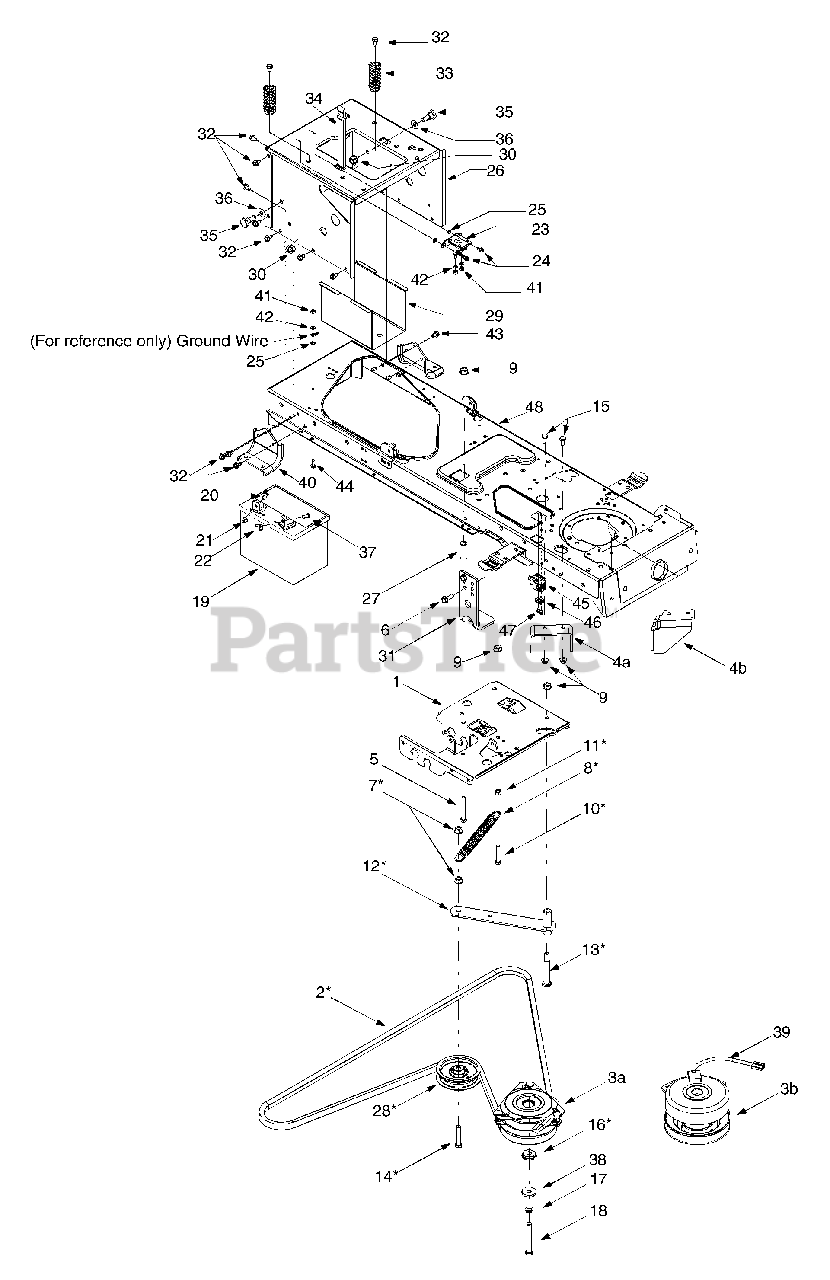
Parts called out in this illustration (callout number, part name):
2	PTO Belt
3A	Elec. PTO Clutch (Mod. Z809H)
3B	Elec. PTO Clutch (Mod. Z809K)
3B	Washer, Flat, 1.031 x 1.62 x .095
6	Hex Head Washer Screw, 5/16-18 x .875
7	Flange Lock Nut, 3/8-16
8	Extension Spring, .62 x 5.62
9	Flange Lock Nut, 5/16-18
10	Hex Cap Screw, 5/16-18 x 1.75
11	Hex Nut, 5/16-18
12	Idler Bracket Assembly
13	Shoulder Screw, 1/2 x 2.5
14	Hex Cap Screw, 3/8-16 x 2.0
15	Hex Cap Screw, 5/16-18 x .625
16	Shoulder Spacer, 1.38 x .445 x .36
17	Lock Washer, 7/16
18	Hex Cap Screw, 7/16-20 x 3.25
19	12-volt Battery, 270 CCA
20	Hex Cap Screw, 1/4-20 x .62
21	Hex Sems Nut, 1/4-20
22	Wing Nut, 1/4-20
23	Solenoid, 12-Volt, 100 Amp
24	Self Tapping Screw, 1/4-20 x .5
25	Lock Washer, 1/4
28	Idler Pulley, 3.5
32	Self Tapping Screw, 5/16-18 x .625
33	Compression Spring, 1.28 x 3.5
34	Battery Strap
35	Shoulder Screw, .625 x .5, 7/16-20
36	Bell Washer, .45 x 1.0 x .062
37	Shoulder Screw, 1/4-20, .25 x .15
38	Flat Washer, .45 x 1.25 x .164
39	Harness Assembly, Electric PTO Clutch
41	Hex Nut 1/4-20
42	Lock Washer
43	TT Screw 5/16-18 x 0.5
44	TT Screw 1/4-20 x 0.75
45	Switch
46	Switch Plate
47	AB Screw #10-16 x 0.5
